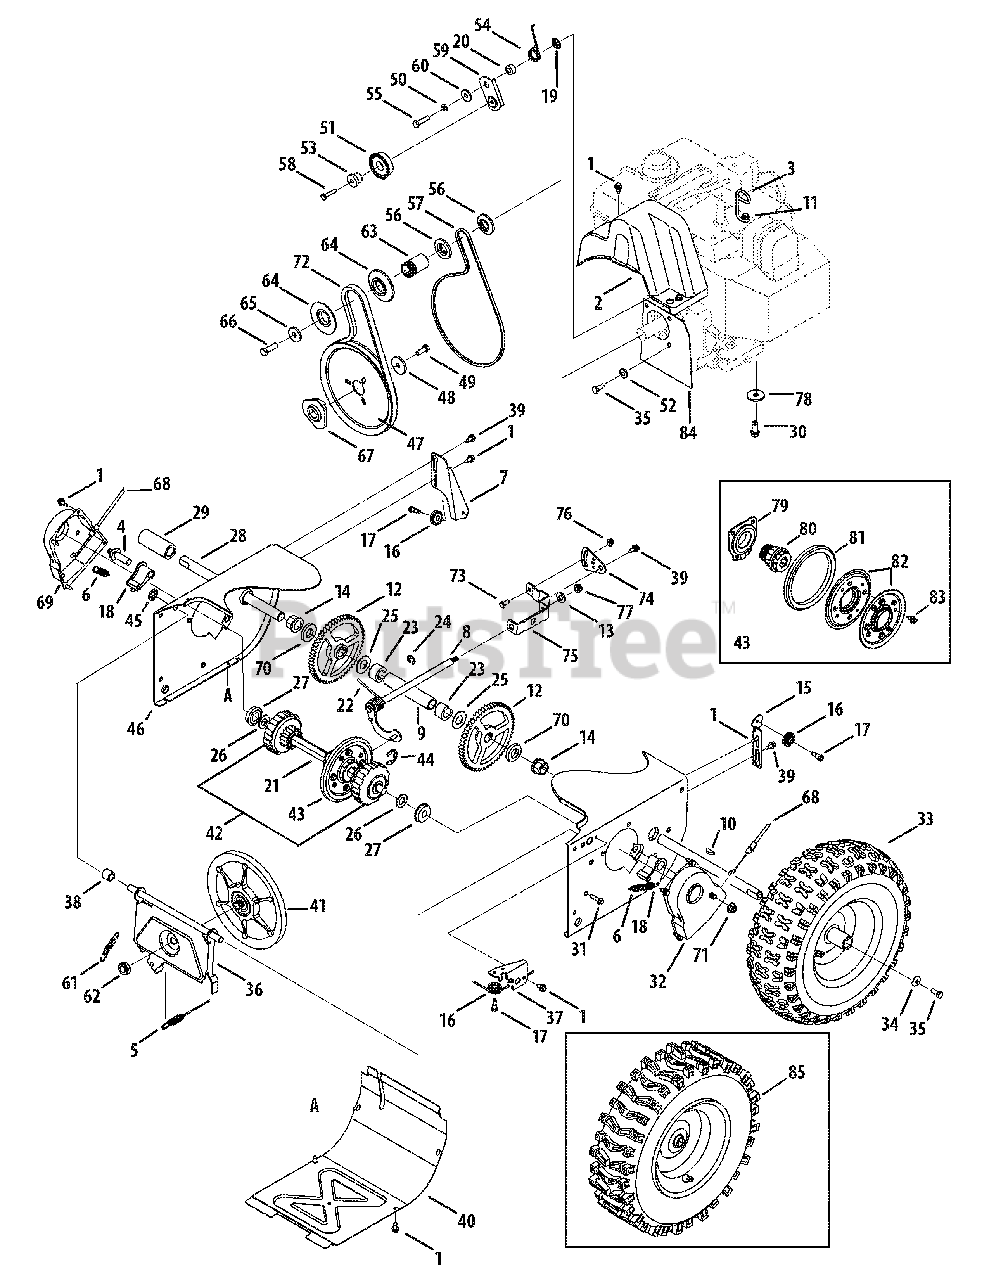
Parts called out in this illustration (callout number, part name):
1	AB Screw, 1/4-20 x 0.625
2	Belt Cover
3	Cable Guide
4	Actuator Shaft
5	Drive Clutch Cable
6	Extension Spring
8	Shift Rod Assembly
9	Axle Support Tube
10	Hi-pro Key
11	TT Screw, 5/16-18 x 1.00
12	Gear, 56T
13	Flat Washer
14	Hex Flange Bearing
16	Cable Roller
17	C Screw, 1/4-28 x 0.375
18	Dogg Assembly - LH
18	Dogg Assembly - RH
20	Spacer
21	Hex Drive
22	Torsion Spring, .750ID x .968 Lg.
24	E Ring
25	Flat Washer, .76 x 1.49 x .06
26	Flat Washer
27	Ball Bearing
28	Axle
30	TT Sems Screw, 3/8-16 x 1.0
31	TT Screw, 1/4-20 x 1.0
34	Bell Washer
35	Hex Bolt, 5/16-24 x 0.75
39	Shoulder Screw
41	Friction Wheel Disc Assembly
42	Drive Shaft Assembly
43	Friction Wheel Assembly
44	Retainer Ring
45	Speed Nut
47	Auger Pulley
48	Flat Washer
49	Hex Bolt, 5/16-24 x 0.875
50	Lock Washer
51	Pulley Assembly
52	Shoulder Spacer
54	Torsion Spring
55	Hex Screw, 5/16-24 x 1.25
56	Pulley Half
57	V-Belt, 2L x 33
58	TT Screw, 1/4-20 x 1.25
59	Drive Clutch Idler Bracket
60	Shoulder Spacer
61	Extension Spring
62	Jam Lock Nut, 5/8-18
64	Pulley Half
65	Flat Washer
66	Hex Bolt, 3/8-24 x 1.25
67	Pulley Adapter
68	Steering Cable
70	Axle Spacer
71	Flange Lock Nut, 3/8-16
72	V-Belt,.500 x 35.00 Lg
73	Hex Screw, 1/4-20 x .620
76	Flange Lock Nut 1/4-20
77	Flange Lock Nut 1/4-20
78	Flat Washer
79	Bearing Assembly
80	Friction Wheel Hub
81	Friction Wheel Rubber
82	Friction Wheel Plate
